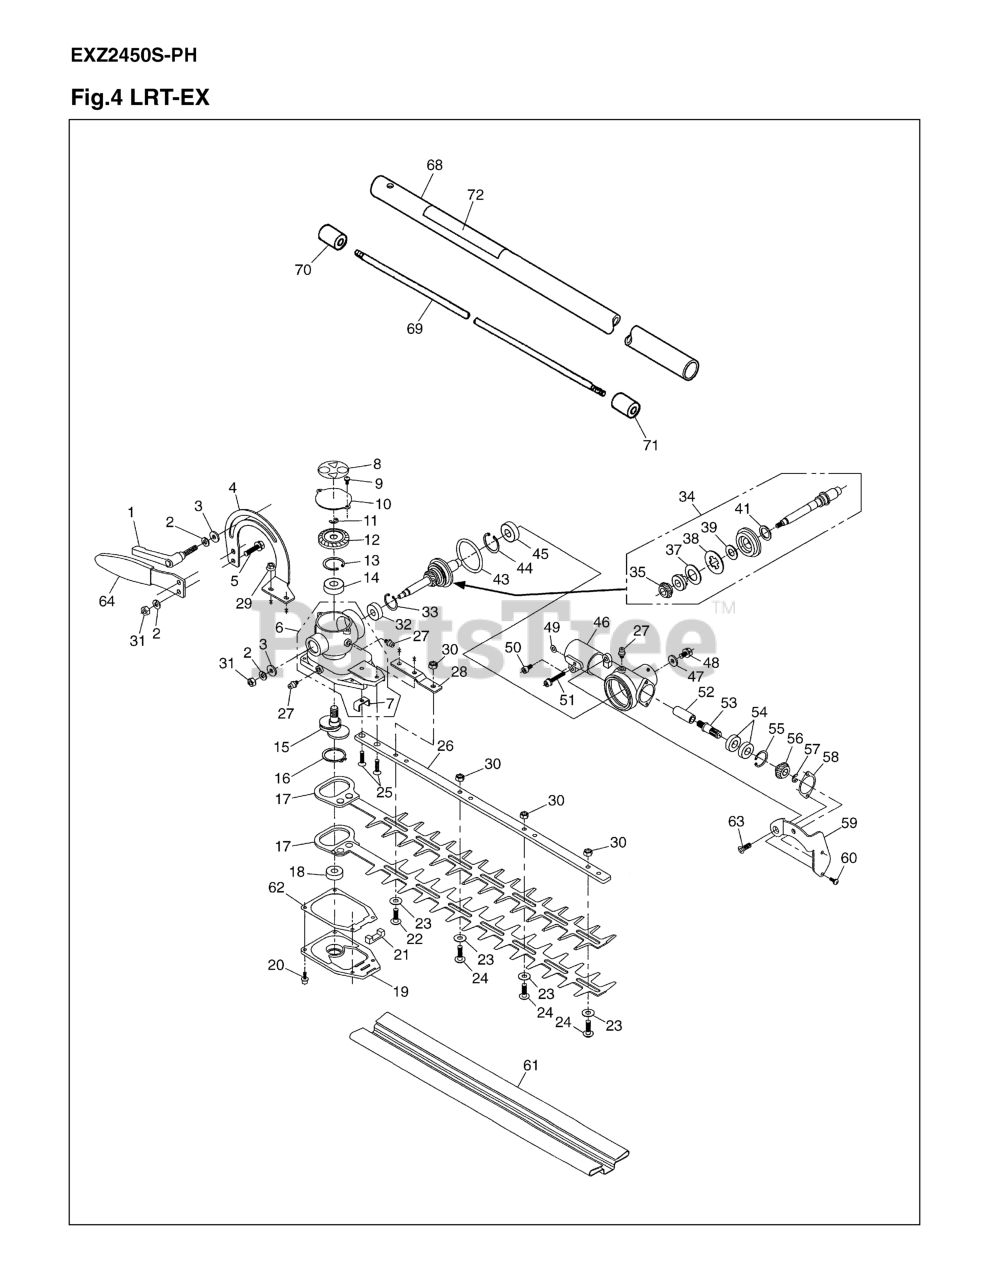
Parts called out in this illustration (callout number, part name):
1	LEVER, CLAMP
2	WASHER M6
3	WASHER, 6X15X2.0
4	ANGLE ADJUSTER
5	BOLT
6	CASING A SET
7	PLATE
9	SCREW, M4 X 8
11	RING, SNAP
12	BEVEL GEAR
13	SNAP RING
14	BEARING
15	CRANKSHAFT
16	SNAP RING
17	BLADE (RPLS -13410) 18
18	BEARING
19	COVER
20	BOLT
21	FELT
23	WASHER
24	SCREW
25	SCREW
26	PLATE, GUIDE
27	FITTING, GREASE
28	PLATE
29	NUT, M5
30	NUT
31	NUT M6
32	BEARING
33	RING, SNAP, M22 x 1.2
35	GEAR (C)
37	SPRING
38	PLATE
39	WASHER
41	WASHER
43	O-RING
44	SNAP RING
45	BEARING
46	CASING N
47	WASHER, 6X15X2.0
49	WASHER
50	BOLT
51	BOLT
52	JOINT
53	GEAR SHAFT B
54	BEARING
55	SNAP RING
56	BEVEL GEAR
57	RING, SNAP
58	PACKING
59	PLATE
60	SCREW, M4 X 10
61	COVER, BLADE
62	GASKET
63	SCREW
64	HANDLE
68	PIPE COMPLETE
69	SHAFT
70	JOINT, SHAFT (RPLS -12240)
71	SPACER
72	PLATE, NAME
